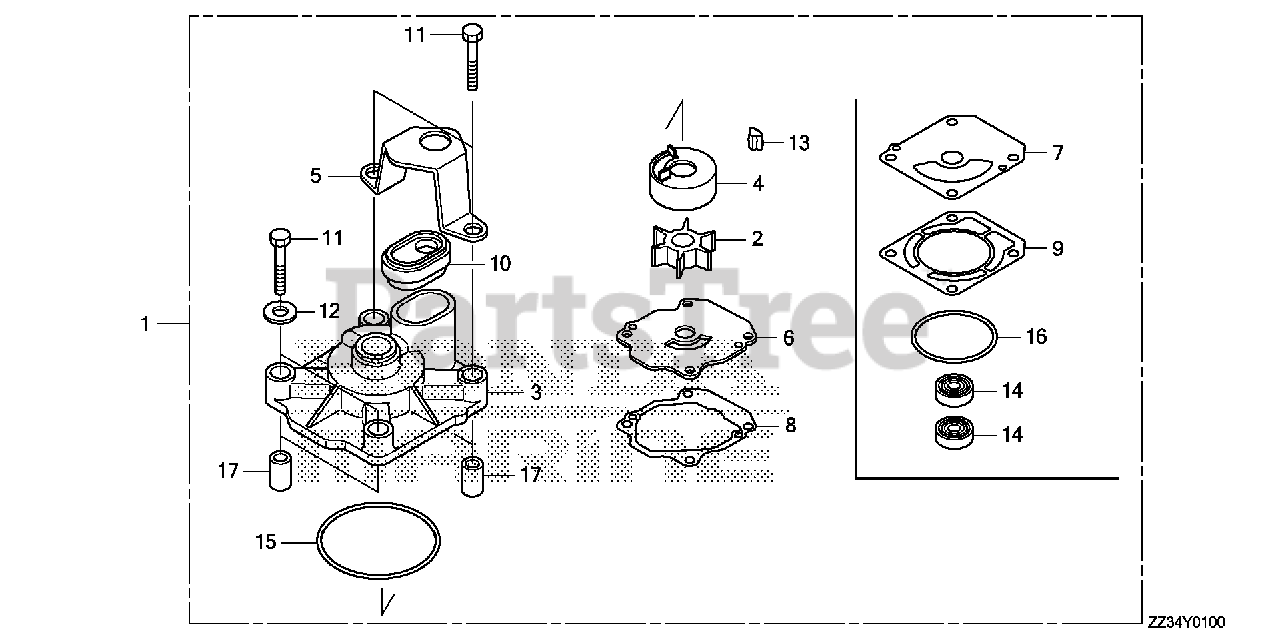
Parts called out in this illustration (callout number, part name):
1	PUMP KIT, IMPELLER (POWER THRUST)
2	IMPELLER, PUMP
3	HOUSING, IMPELLER
4	LINER, PUMP
5	HOLDER, WATER TUBE SEAL
6	COVER, IMPELLER
7	GASKET B, IMPELLER (POWER THRUST)
9	GASKET, WATER PUMP
10	RUBBER, WATER TUBE SEAL
11	BOLT, HEX. (8X55)
12	WASHER (8MM)
13	KEY, WOODRUFF
14	SEAL, WATER (23X36X6)
15	O-RING, WATER PUMP
16	O-RING (58.5X3.5)
17	COLLAR, DISTANCE
